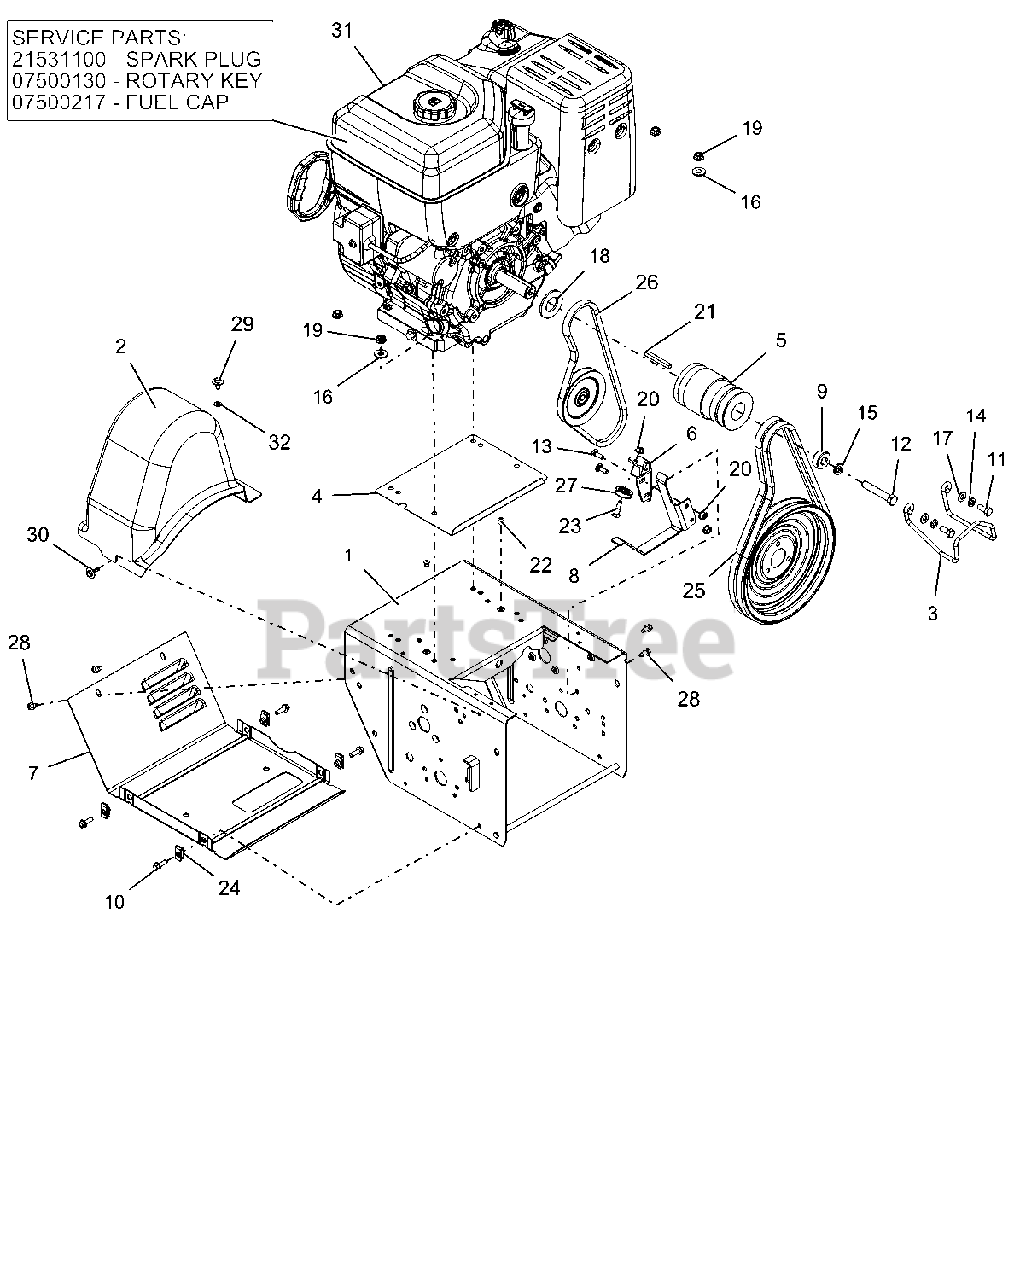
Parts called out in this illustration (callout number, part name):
1	PRO HYDRO FRAME, MAIN
2	COVER, BELT-LARGE PRO
3	FINGER, BELT
4	BAFFLE,ENGINE-PRO SERIES
5	SHEAVE, COMBO HYDRO TRACK 4L
6	BRACKET, CLUTCH CABLE
7	COVER, BOTTOM - VENTILATED
8	FINGER, BELT - FLAT
9	BSHG-SPACER .47X1.25X.50
10	BLT-HEX .25-20X.75 HWH YZ GR5
11	BLT-HEX .31-24X.75 YWZC GR5
12	BLT-HEX .44-20X2.50 GR5 YWZC
13	@BLT-RDHDSQNK .25-20X.75 G5YZ
14	WSHR-LK .312X.097 HVY YWZC
15	@WSHR-LK .44X.109 REG YWZC
16	@WSHR-FL-STL.38X.875X.083 YWZC
17	@WSHR-FL-STL.344X.688X.065YWZC
18	WSHR-FL-STL- 1.062X2.0X.134 YZ
19	@NUT-LK-CTR-FLG .31-18 YZ GR F
20	@NUT-LK-TOP-FLG .25-20 YWZC
21	KEY .25X.25X2.25
22	RVT-POP .187 YZ
23	BOLT, SHLDR-.375X.375X.25-20
24	NUT-RTNR .25-20X.56
25	V-BELT, HA-RAW EDGE (SET)
26	V-BELT, 4L-WRAPPED
27	PULLEY, CABLE
28	SCR-TAP .25-20X.50 HWH TR YWZ
29	SCR-TAP .25-20X.50 LGHWH TR YZ
30	SCR-TAP .25-20X.5 CAPTIVE
31	PLUG, SPARK 20HP B&S VANGUARD
31	KEY, IGNITION ROTARY B&S
31	ENGINE, BRIGGS PF 2100, 120V
31	CAP, FUEL - BRIGGS & STRATTON
32	NUT-PUSH .25X.50 O.D.
